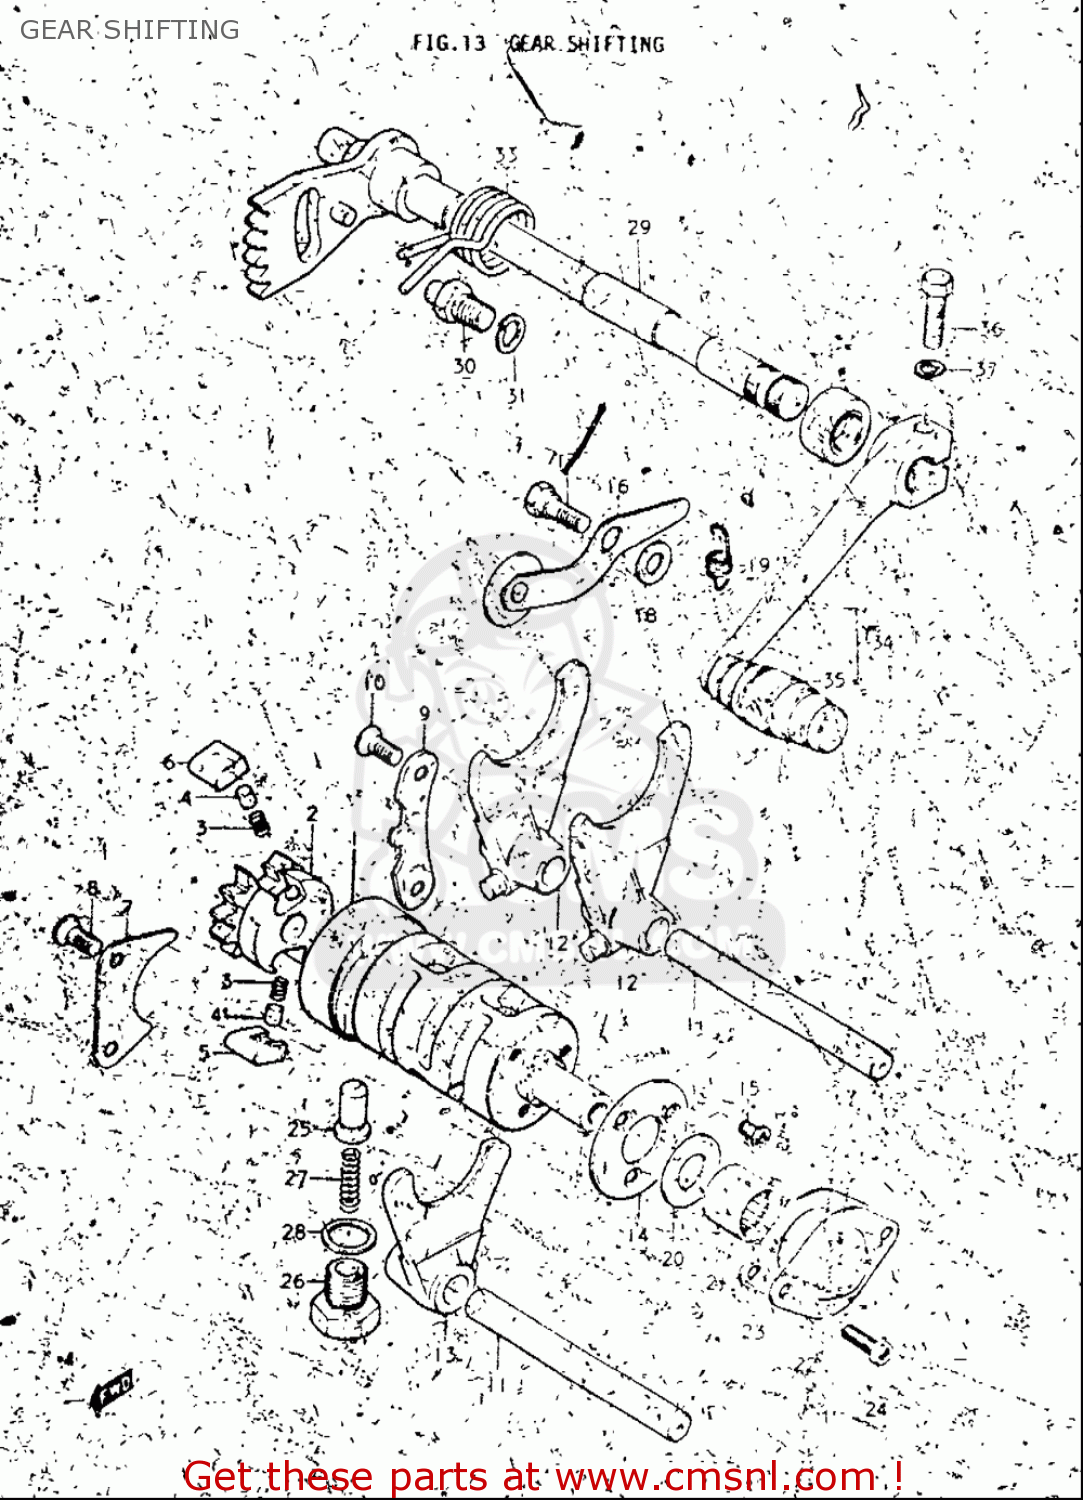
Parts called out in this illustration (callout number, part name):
2	GEAR,GEAR SHIFT CAM DRIVEN
3	SPRING
4	PIN(5X8)
5	PAWL,GEAR SHIFT NO.1
6	PAWL,GEAR SHIFT NO.2
7	LIFTER,GEAR SHIFT POLE
8	SCREW
10	SCREW
11	SHAFT,GEAR SHIFT FORK
15	SCREW
17	BOLT(6X16.1)
18	WASHER
19	SPRING
22	CAP,CAM PIVOT
24	SCREW
25	STOPPER,GEAR SHIFT CAM NO.2
26	HOLDER,GEAR SHIFT CAM STOP SPR
27	SPRING
28	GASKET(14X19.2X2) (NAS)
29	SHAFT,GEAR SHIFT
30	STOPPER,GEAR SHIFT ARM
31	WASHER,LOCK
32	SEAL,OIL (12X22X9)
33	SPRING
34	LEVER ASSY,GEAR SHIFT
35	RUBBER,GEAR SHIFT PEDAL
36	BOLT
37	WASHER,LOCK
